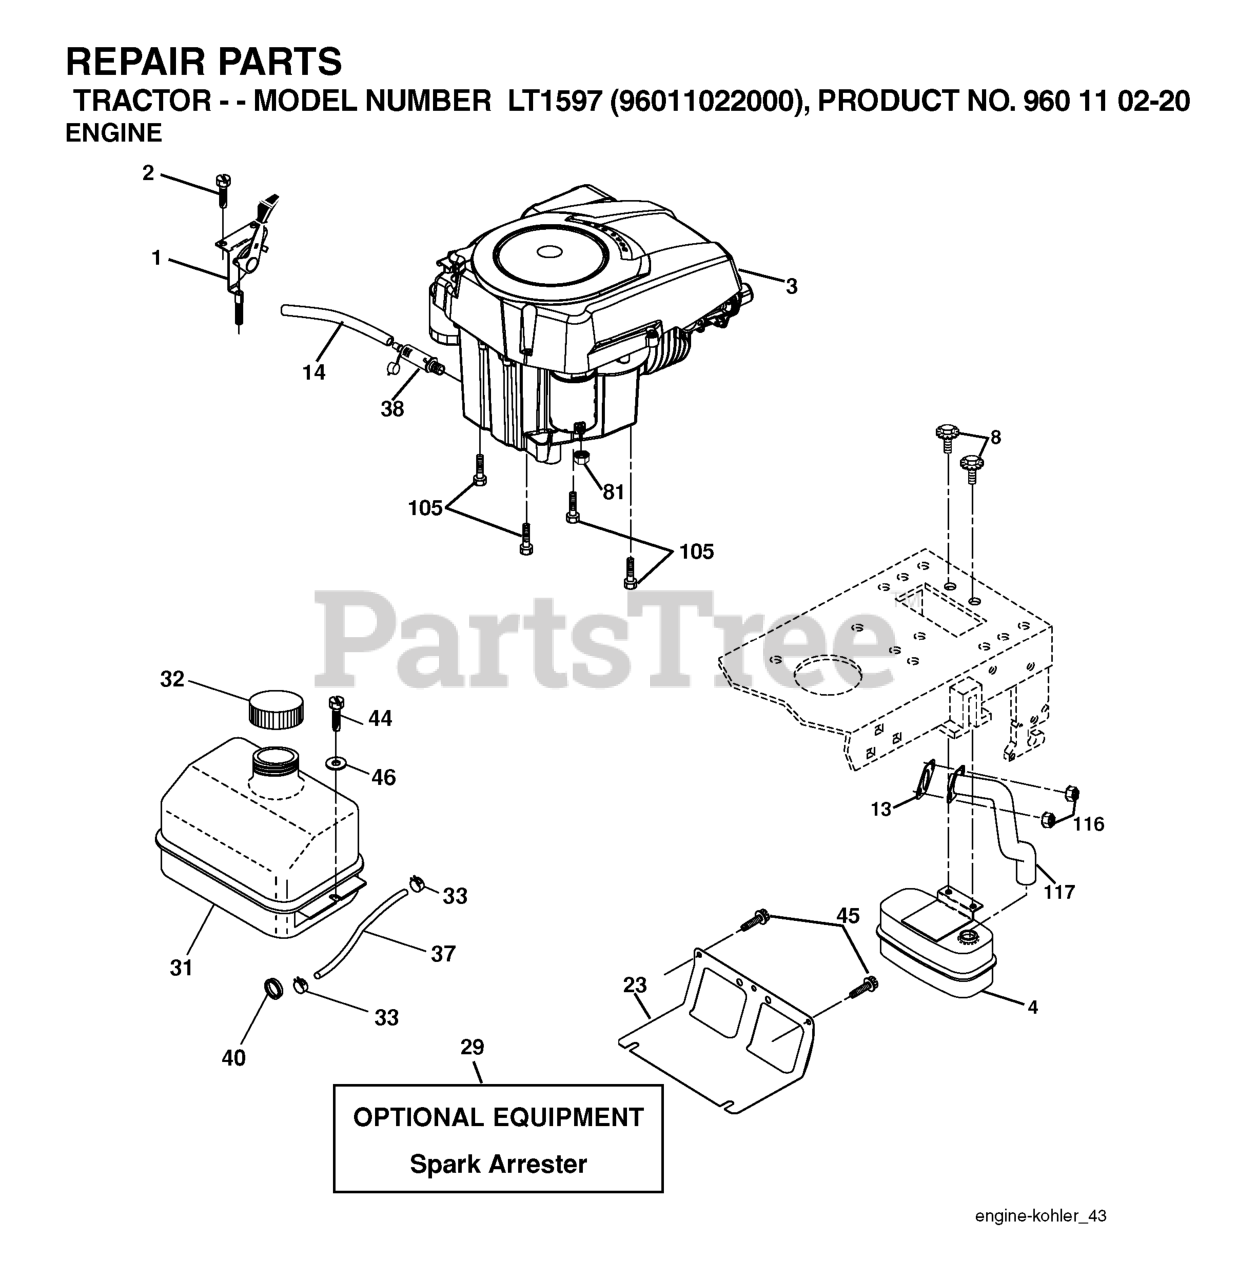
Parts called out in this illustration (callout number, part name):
2	SCREW
4	MUFFLER.SINGLE.CYL.KOHL/B&S
8	BOLT.5/16-18UNCX3/4 W/SEMS.BLK
13	GASKET.EXHAUST.KOHLER
14	TUBE, DRAIN OIL ASM.
23	SHIELD.BROWNING.DBR.GUARD
29	KIT.SPARK ARRESTOR 794945 B&S
31	TANK.ASM.FUEL.FRONT.W/CAP
32	FUEL CAP
33	HOSE CLAMP
37	LINE.FUEL.20
38	PLUG DRAIN OIL EASY
40	BUSHING.SNAP.NYL.BLK.
44	SCREW HEXWSHR 1/4-20X3/4
45	SCREW, 3/8-16X3/4
81	NUT
105	SCREW 3/8-16X1
116	NUT.HEX.FLANGE.TOPLOCK
117	RP.TUBE.EXHAUST.KOHL.COURAGE
